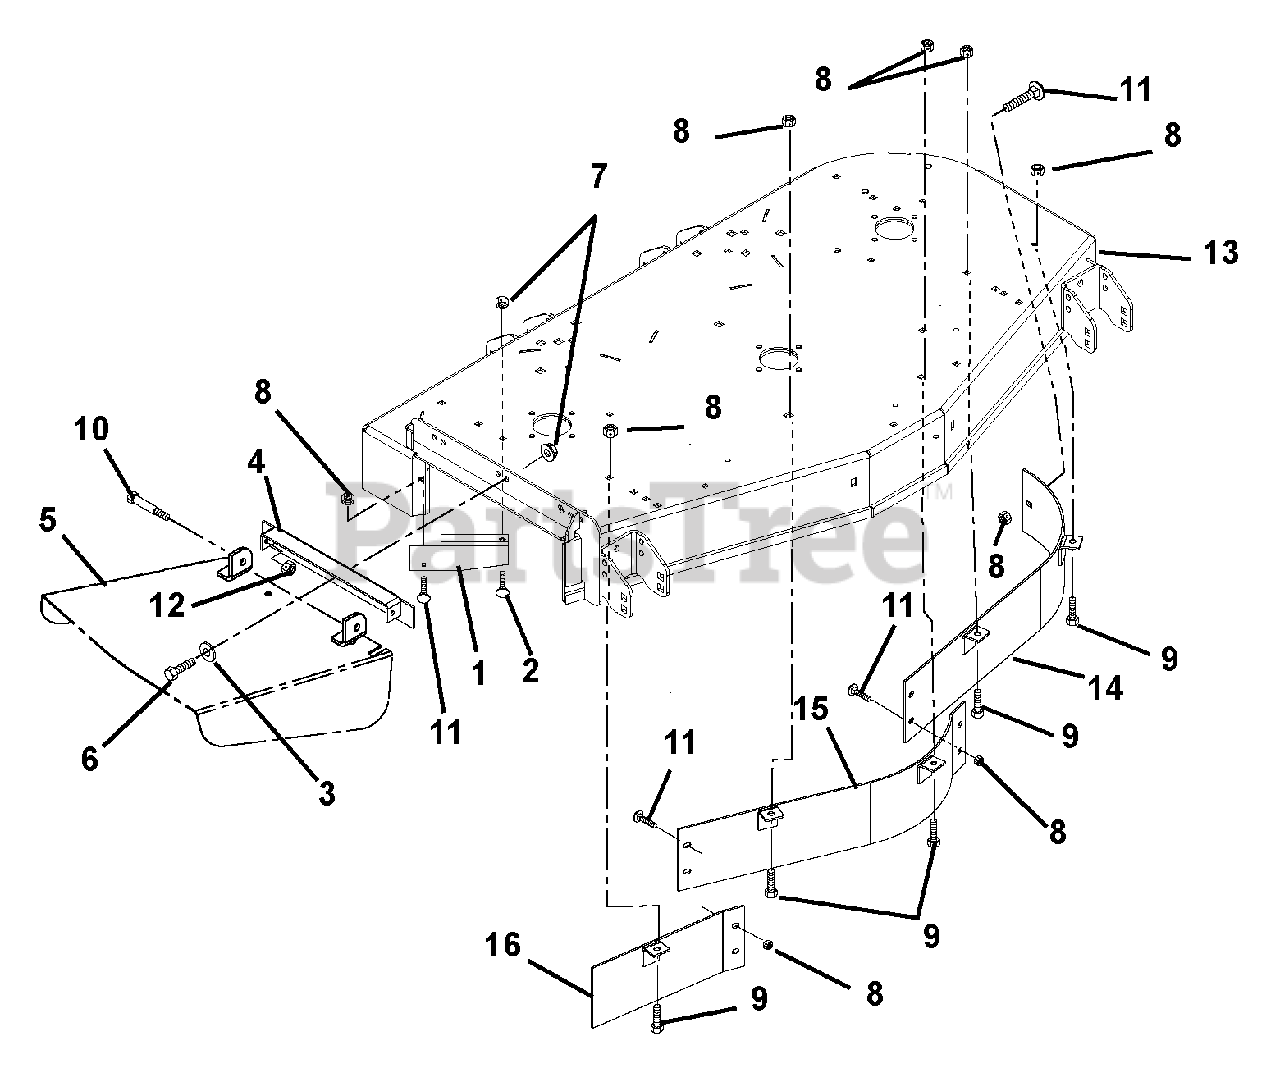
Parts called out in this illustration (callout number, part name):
1	Deflector, 52"
1	Deflector, 60"
1	Deflector, 44"
2	Bolt, Round Head Square Neck .38-16 x 1.00 Grade 5
3	Washer, Flat Steel .38 x .875 x .083
4	Weldment Discharge Chute Bracket
5	Chute, Discharge
6	Bolt, Hex .38-16 x 1.00 Grade 5
7	Nut, Locking Top Flange .38-16
8	Nut, Locking Top Flange .31-18
9	Bolt, Hex .31-18 x .75 Grade 5
10	Bolt, Shoulder .38-16 x .50 Socket Head
11	Bolt, Round Head Square Neck .31-18 x .75 Grade 5
12	Nut, Locking Center .38-16
13	Weldment, 52" Mower Deck
13	Weldment, 60" Mower Deck
13	Weldment, 44" Mower Deck Float
13	Weldment, 48" Mower Deck
14	Baffle, Left Front - 52"
14	Baffle, Left Front - 60"
14	Baffle, Left Front - 44"
14	Baffle, Left Front - 48"
15	Weldment, Baffle Center Front - 52"
15	Weldment, Baffle Center Front - 60"
15	Weldment, Baffle Center Front - 44"
15	Weldment, Baffle Center Front - 48"
16	Weldment, Baffle Right Front - 52"
16	Weldment, Baffle Right Front - 60"
16	Weldment, Baffle Right Front - 44"
16	Weldment, Upper Baffle Right - 48"
